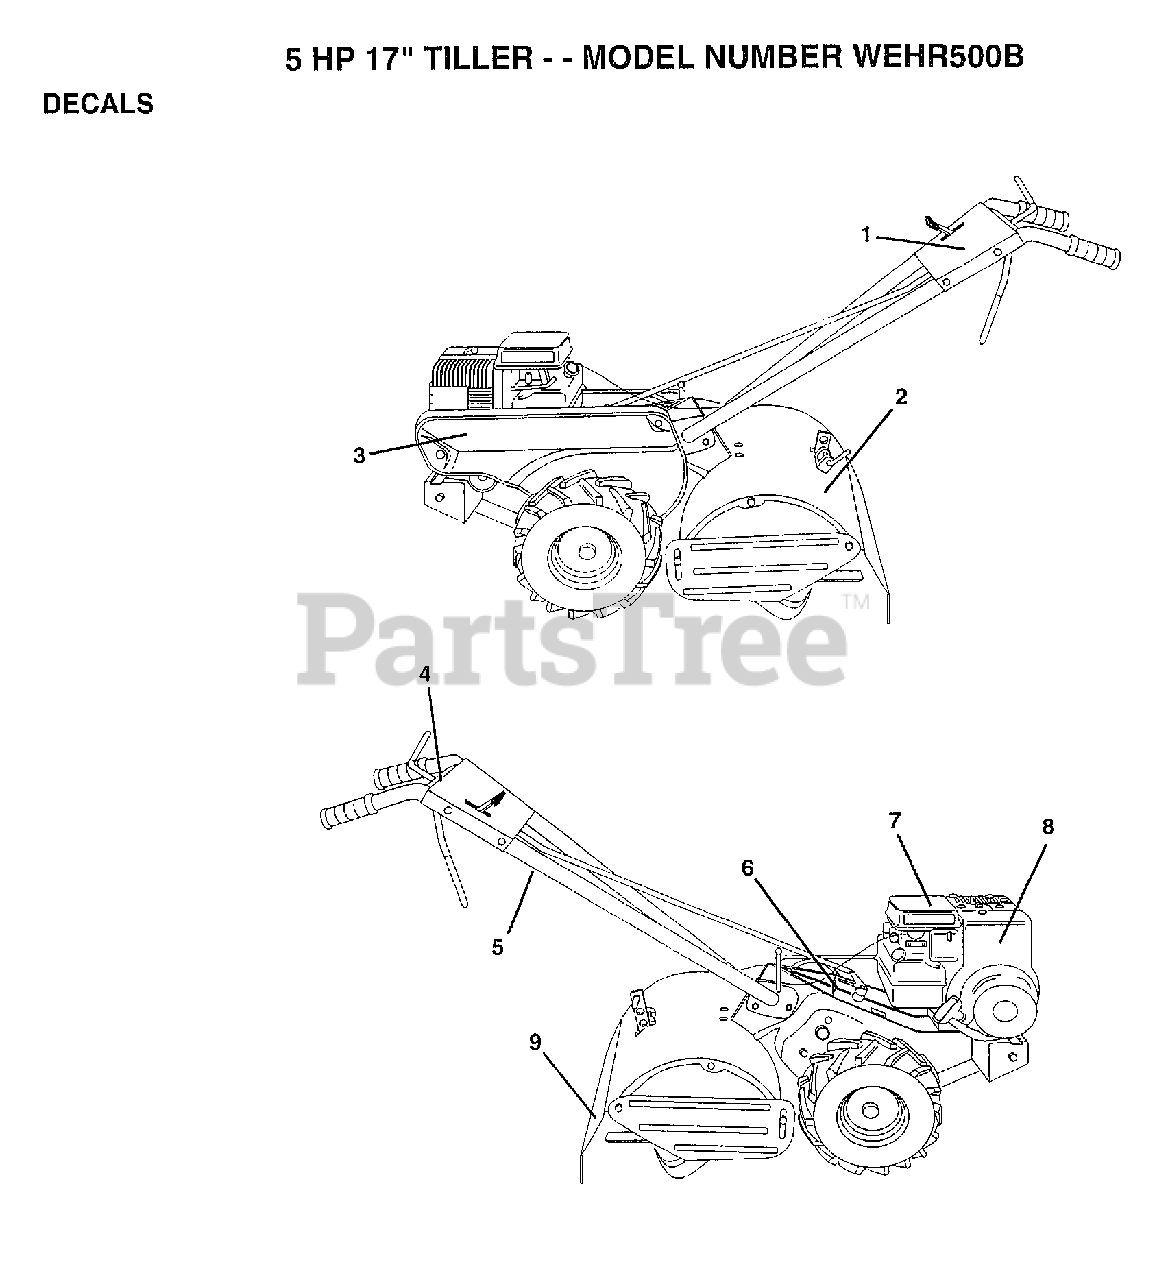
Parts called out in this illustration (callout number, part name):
1	DECAL LOGO 17 5HP
2	DECAL SHIELD TINE
3	DECAL BELT GUARD
4	DECAL.CONTROL
5	DECAL.HAND.PLACE
6	DECAL CRT
7	DECAL.CAUTION.E/S
9	DECAL.WARN.ROT.TI
